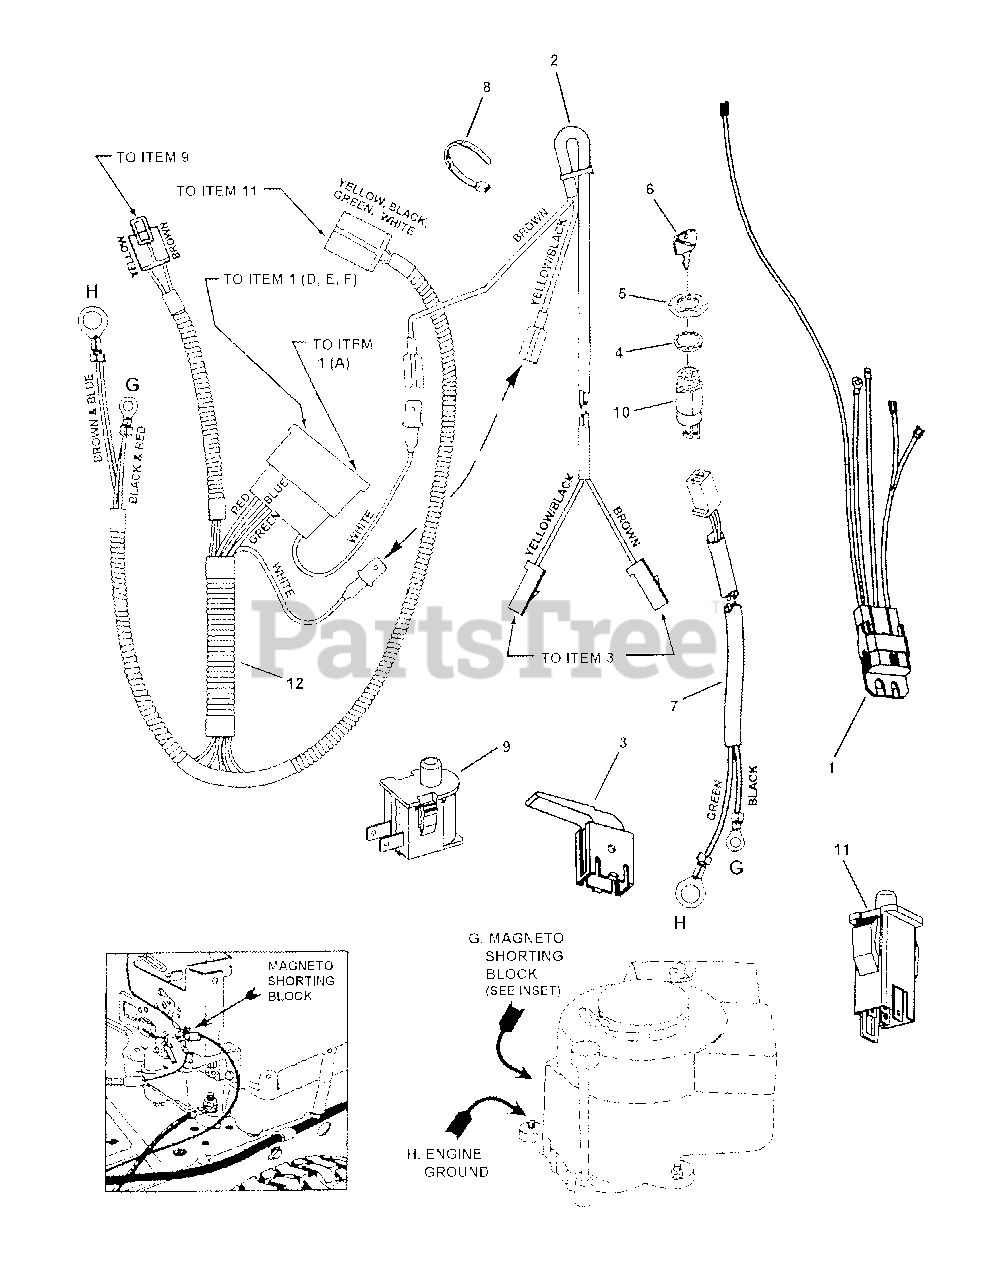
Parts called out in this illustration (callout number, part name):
1	INTERLOCK MODULE, Briggs
2	HARNESS, (Deck Interlock Wiring)
3	SWITCH, Deck Interlock (NO)
4	WASHER, 5/8" Internal Tooth Lock
5	NUT, 5/8-32 Hex
6	KEYS, Blister Pk (KIDS+MWRS DON'T MIX) English/Spanish (set of two, one coated)
7	HARNESS, Ground (Recoil Start)
8	CABLE TIE, 7"
9	SWITCH, Seat (NC)
10	SWITCH, Ignition (2-pole) (Recoil Start)
11	SWITCH, Operator Presence Control (OPC) Traction (NC/NO)
12	HARNESS, Operator Presence Control (OPC) Wire
